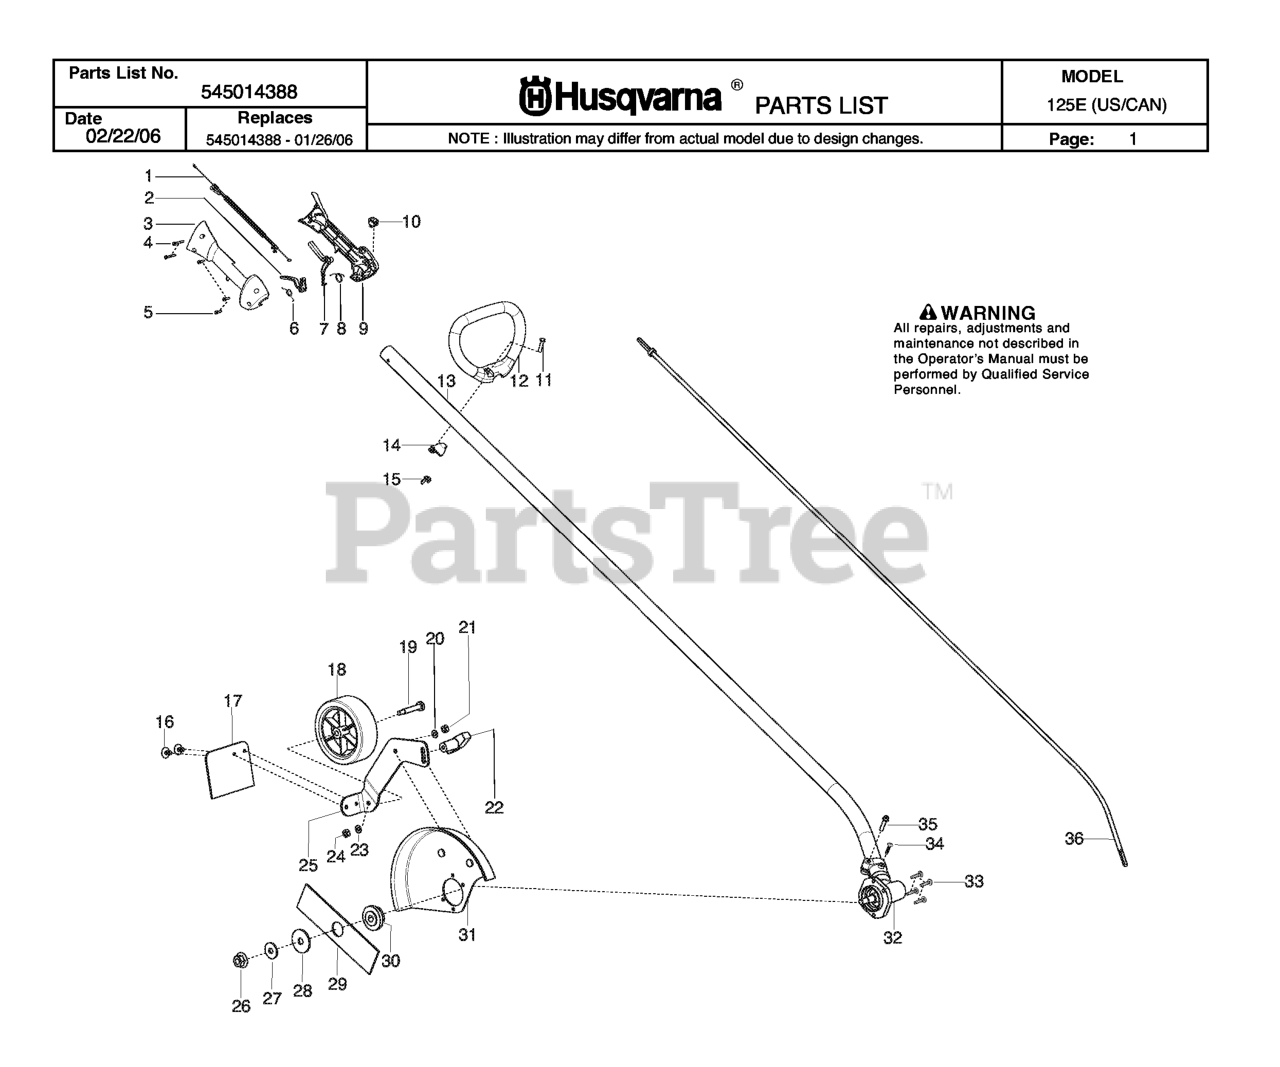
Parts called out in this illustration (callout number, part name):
1	%ASSY CABLE WIRE HARNESS
2	TRIGGER THROTTLE
3	HOUSING-THROTTLE RH
5	SCREW M4 X 1.75 PT 16MM
6	SPRING TRIGGER
7	THROTTLE LOCKOUT
8	SPRING LOCKOUT
9	HSG THROTTLE LH
10	KIT SWITCH
11	BOLT, TYPE 2
13	KIT-DRIVESHAFT
14	CLAMP ASSIST HANDLE
15	WINGNUT, TYPE 2
16	FASTENER MUD FLAP
17	KIT MUD FLAP
18	WHEEL-4"(FRONT)(RUBBER)
19	BOLT-SHOULDER AXLE
25	WHEEL BRKT ADJ
26	NUT-FLANGE (LH)
27	WASHER BELLVILLE
28	WASHER-FLAT.
31	KIT - EDGER GUARD
32	KIT GEARBOX EDGER HUSQ
33	SCR 10-24 MS LDK PAN PH
34	SCREW 8-16 X 9/16 (PLAS
35	SCREW - CARB. ADAPTOR
36	FLEXSHAFT 57"
